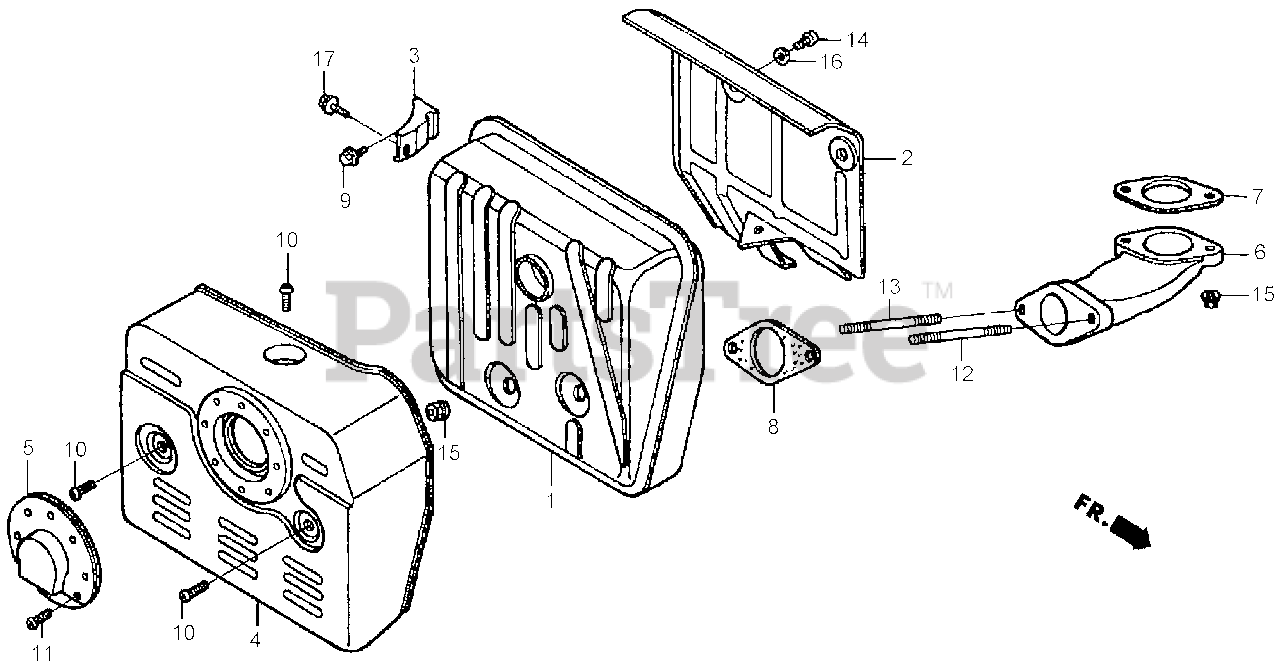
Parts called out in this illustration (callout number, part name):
1	MUFFLER
2	SEPARATOR-MUFFLER
3	STAY-MUFFLER
4	PROTECTOR-MUFFLER
5	CAP-MUFFLER
6	PIPE-EXHAUST
7	GASKET-PIPE, EXHAUST
7	GASKET-PIPE, EXHAUST (WACKER)
8	GASKET-PIPE, EXHAUST
9	BOLT-FLANGE (8X16)
10	SCREW-TAPPING (5X8)
11	SCREW-TAPPING (4X6)
12	BOLT-STUD (8X60)
13	BOLT-STUD (8X70)
14	SCREW-PAN (6X6)
15	NUT-FLANGE (8MM)
16	WASHER-PLAIN (6MM)
17	BOLT-FLANGE (8X14)
